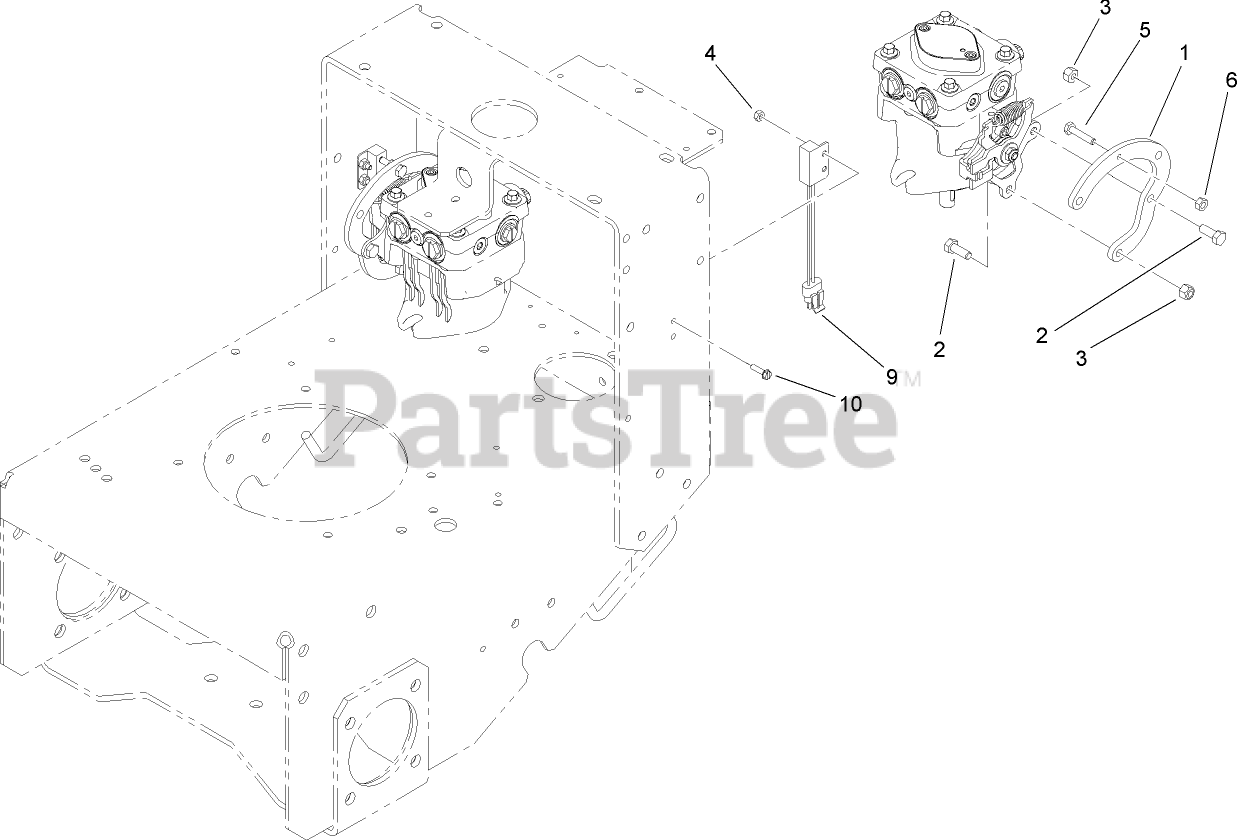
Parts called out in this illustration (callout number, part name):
1	BRACKET-ADAPTER, PUMP
2	SCREW-HH
3	NUT-LOCK, NI
4	NUT-LOCK, NI
5	SCREW-HH
6	NUT-HEX
9	SWITCH-PROXIMITY
10	SCREW-HWH
